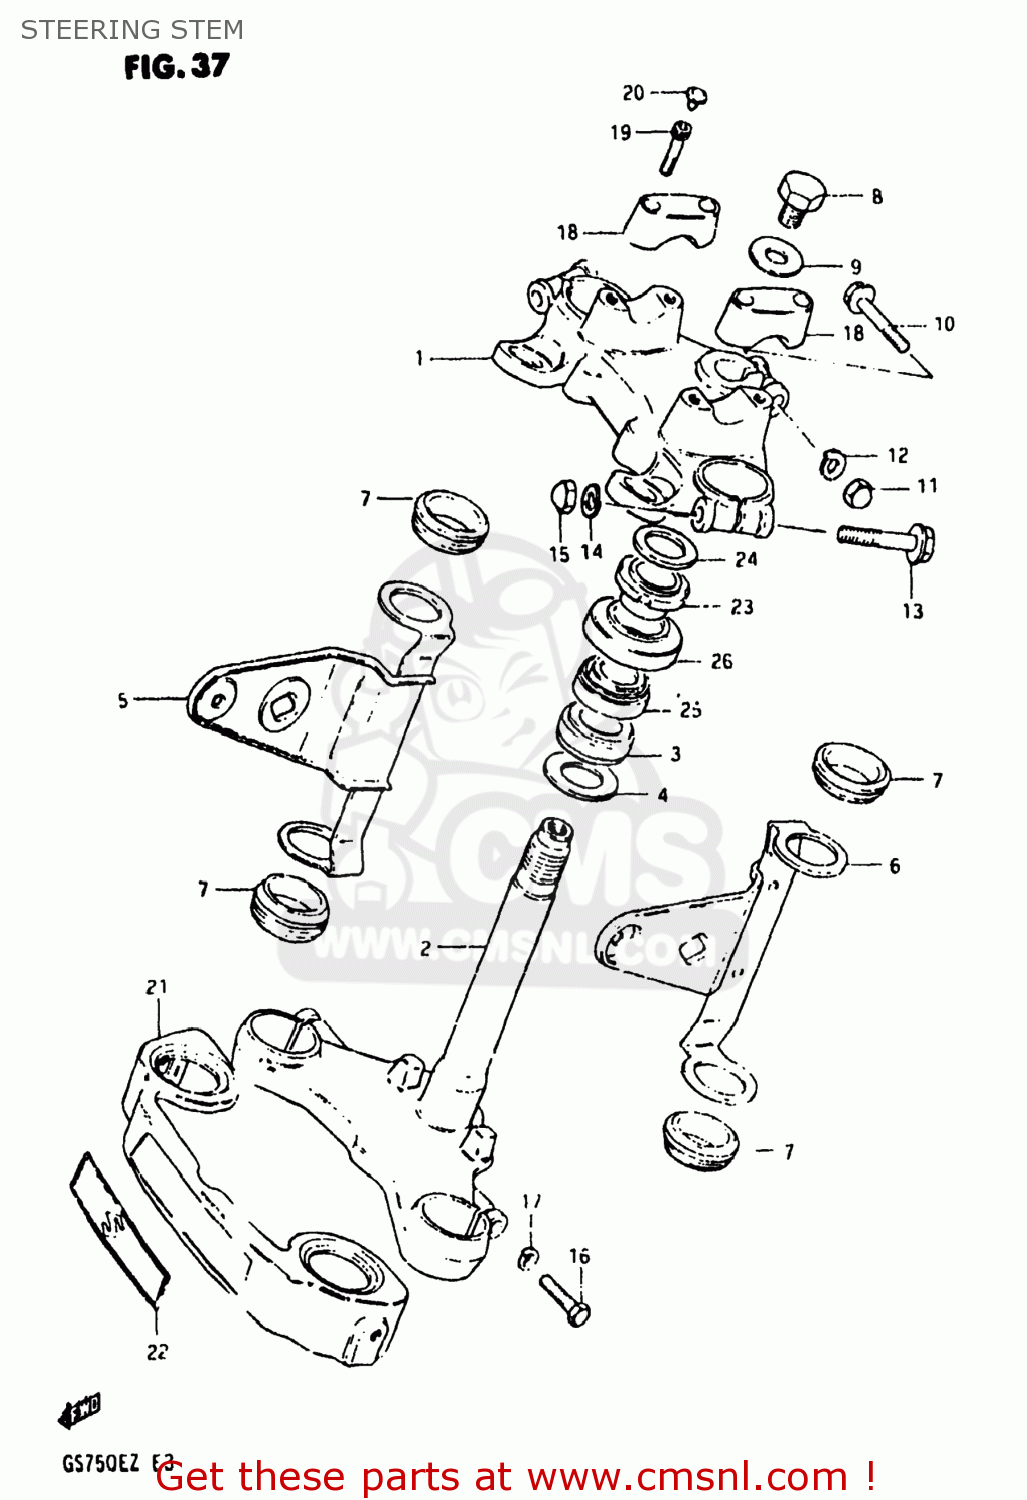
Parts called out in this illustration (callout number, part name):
1	HEAD,STEERING STEM
2	STEM,STEERING
3	BEARING
4	WASHER,THRUST
5	BRACKET,HEADLAMP,RIGHT
6	BRACKET,HEADLAMP,LEFT
7	CUSHION,HEADLAMP BRACKET
8	BOLT 12X20
9	WASHER (12.5X26X1.6)
10	BOLT
11	NUT,M8X1.25X12
12	LOCK WASHER
13	BOLT 10X55
14	LOCK WASHER
15	NUT
16	BOLT 8X40
17	LOCK WASHER
18	HOLDER,HANDLEBAR(BLACK)
19	BOLT
20	CAP(OD:14.5)
21	COVER,FRONT FORK
22	EMBLEM,FRONT FORK COVER
23	NUT,STEERING STEM
24	WASHER(18.5X24X1)
25	TAPER,ROLLER BEARING
26	DUST SEAL,STEERING UPR
